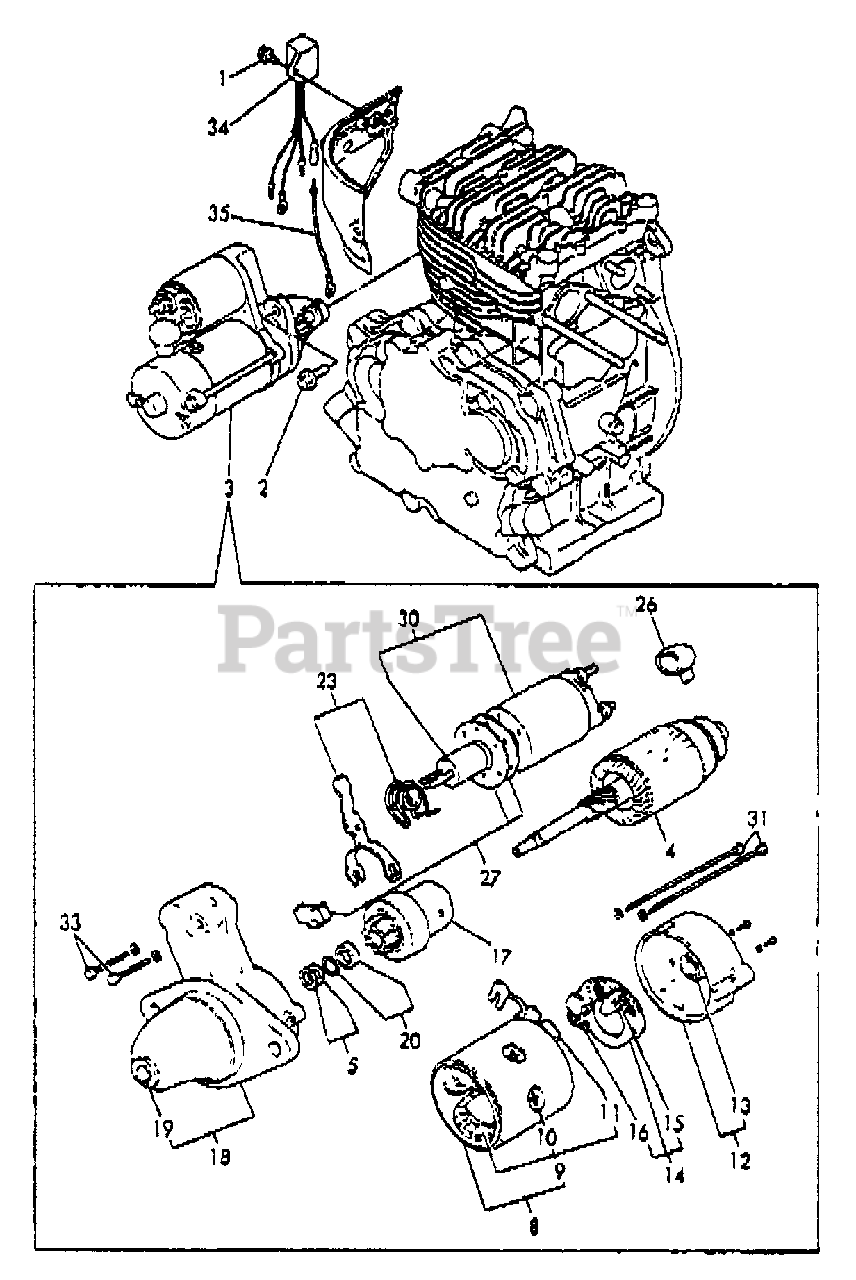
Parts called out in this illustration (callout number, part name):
1	BOLT - 6×12 -- PLATED
2	BOLT - 8×20 -- PLATED
3	STARTING MOTOR
4	ARMATURE ASSY
5	THRUST WASHER KIT
9	IGNITION COIL ASSY
10	SCREW, POLE CORE
11	BRUSH - ( + )
12	REAR COVER ASSY
13	METAL
14	HOLDER ASSY, BRUSH
15	BRUSH(-)
16	SPRING, CHOKE
17	PINION ASSY
18	GEAR CASE ASSY
19	METAL
20	STOPPER SET, PINION
23	LEVER SET, SHIFT
26	CAP, TERMINAL
27	COVER SET, DUST
30	SWITCH ASSY, MAGNET
31	THROUGH BOLT
33	BOLT - 6×32
34	RECTIFIER
35	WIRE
